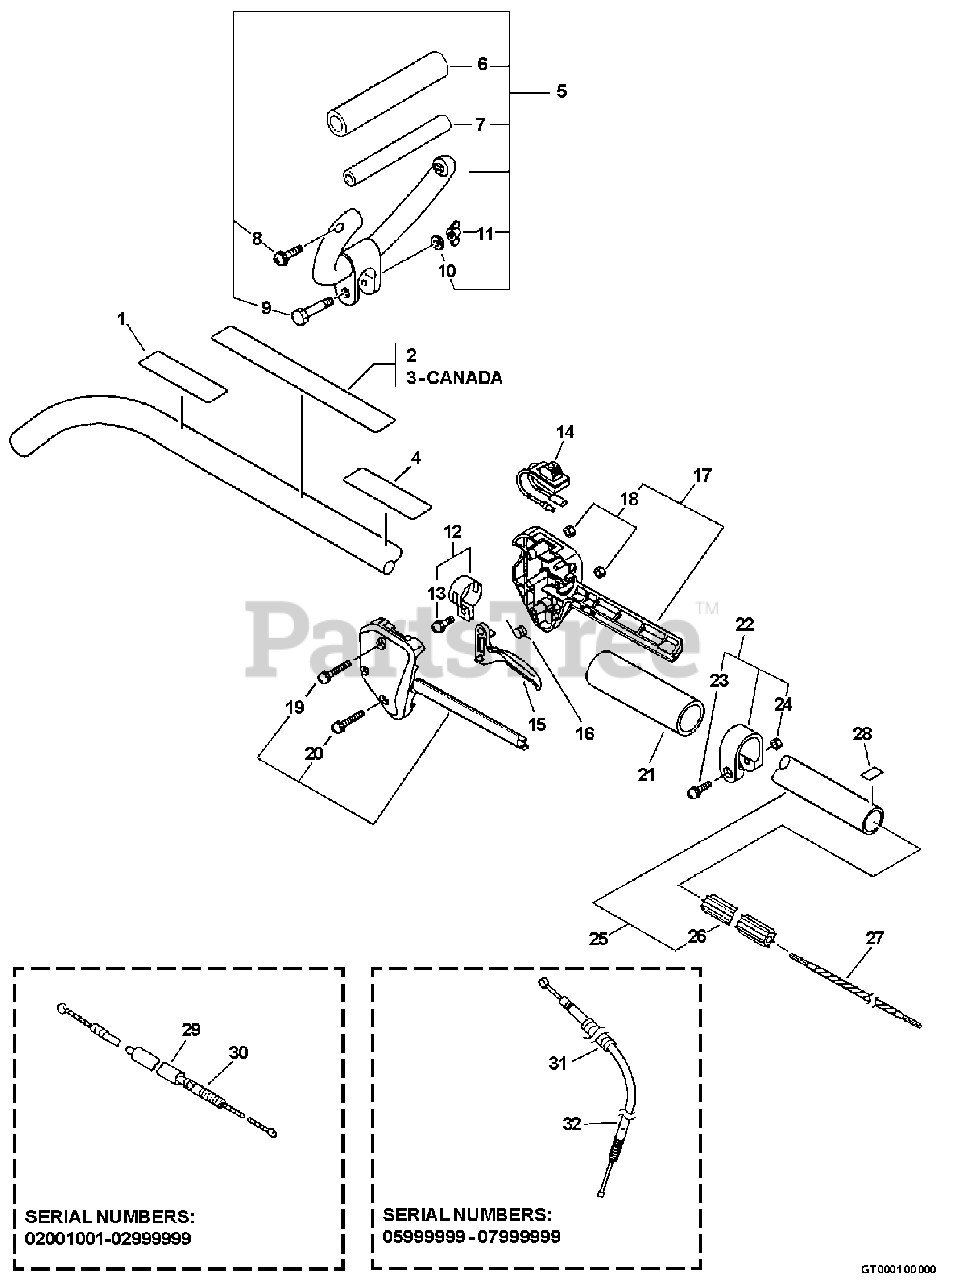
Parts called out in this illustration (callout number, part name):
1	LABEL, CAUTION
2	LABEL, CAUTION
3	LABEL - CAUTION
4	LABEL, HANDLE LOCATION
5	LOOP HANDLE ASSY
6	GRIP, HANDLE
8	SCREW 5×30
9	BOLT - 6×40
10	WASHER 6.5×11.5×0.8
11	NUT, WING 6
12	CLAMP KIT
13	SCREW 5×14
14	SWITCH, ON-OFF
15	TRIGGER, THROTTLE
16	SPRING, TORSION
17	THROTTLE BRACKET SET
18	NUT M5
19	SCREW 5×35
20	SCREW 5×25
21	GRIP, HANDLE
22	CLAMP KIT
23	SCREW 5×28
24	NUT M5
25	MAIN PIPE ASSY
26	LINER - FLEXIBLE
27	DRIVESHAFT - FLEXIBLE
28	LABEL - ALIGNMENT
29	TUBE, FLEXIBLE
30	CABLE, THROTTLE
31	TUBE, FLEXIBLE
32	CABLE, THROTTLE
